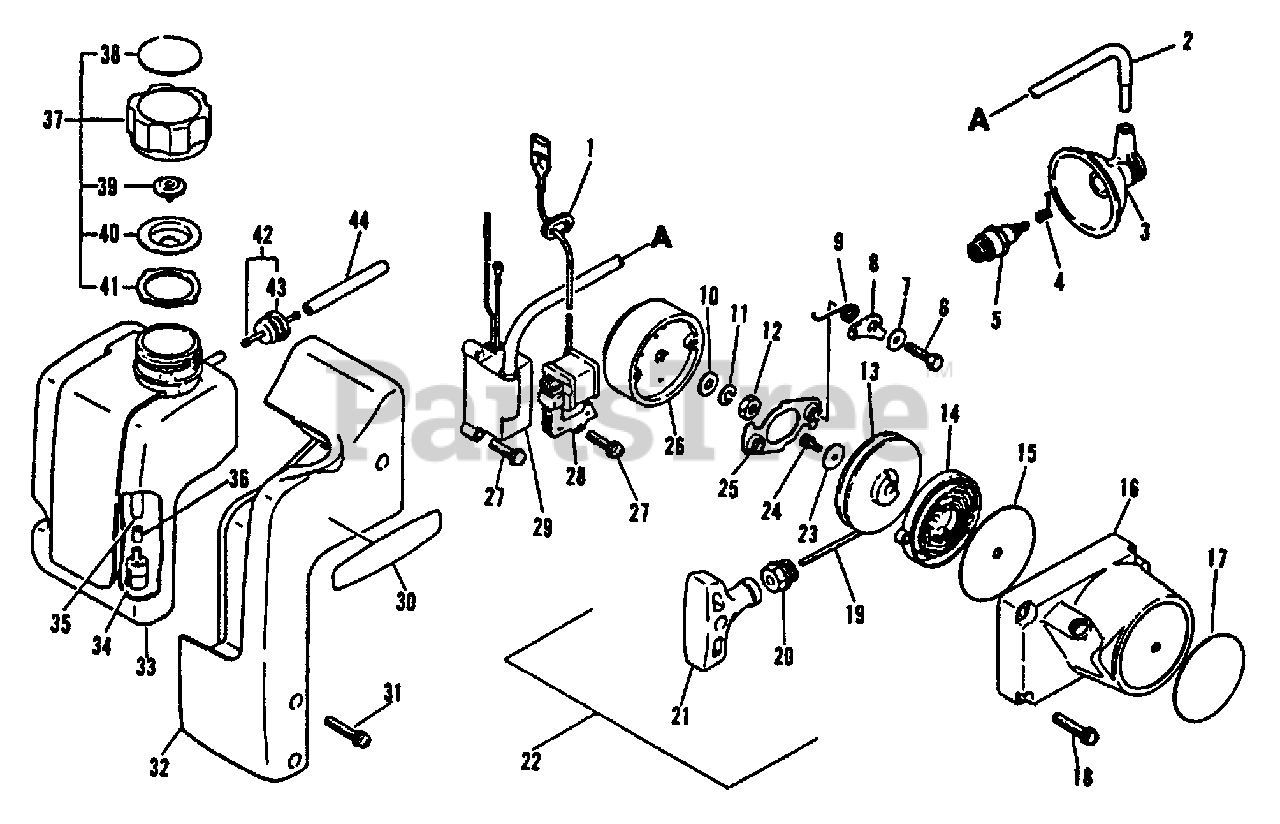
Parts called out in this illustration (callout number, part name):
3	CAP, SPARK PLUG
4	TERMINAL, SPARK PLUG
5	SPARK PLUG - BPM7A
6	BOLT - 5×20
7	WASHER 5.5×12×0.8
8	PAWL, STARTER
9	SPRING, RETURN
10	WASHER 8.5×16×1.2
11	WASHER, SPRING 8
12	NUT 8×1.25
13	REEL, ROPE
14	SPRING, RECOIL
16	CASE, STARTER
17	LABEL - ECHO
18	SCREW 5×25
20	GUIDE, ROPE
21	GRIP, STARTER
22	STARTER ASSY
23	WASHER 4.1×15.5×1T
24	SCREW 4×10
25	HOLDER, PAWL
26	FLYWHEEL
27	SCREW 4×20
28	COIL, EXCITER
29	COIL, IGNITION
30	LABEL - ECHO
31	SCREW 4×25
32	BRACKET, FUEL TANK
33	TANK, FUEL
34	FILTER, FUEL
35	PIPE, FUEL
36	VALVE, CHECK
37	CAP ASSY
38	LABEL - FUEL MIX
39	VENT ASSY
40	HOLDER, CHECK VALVE
41	GASKET, FUEL CAP
42	GROMMET KIT
44	PIPE, FUEL
